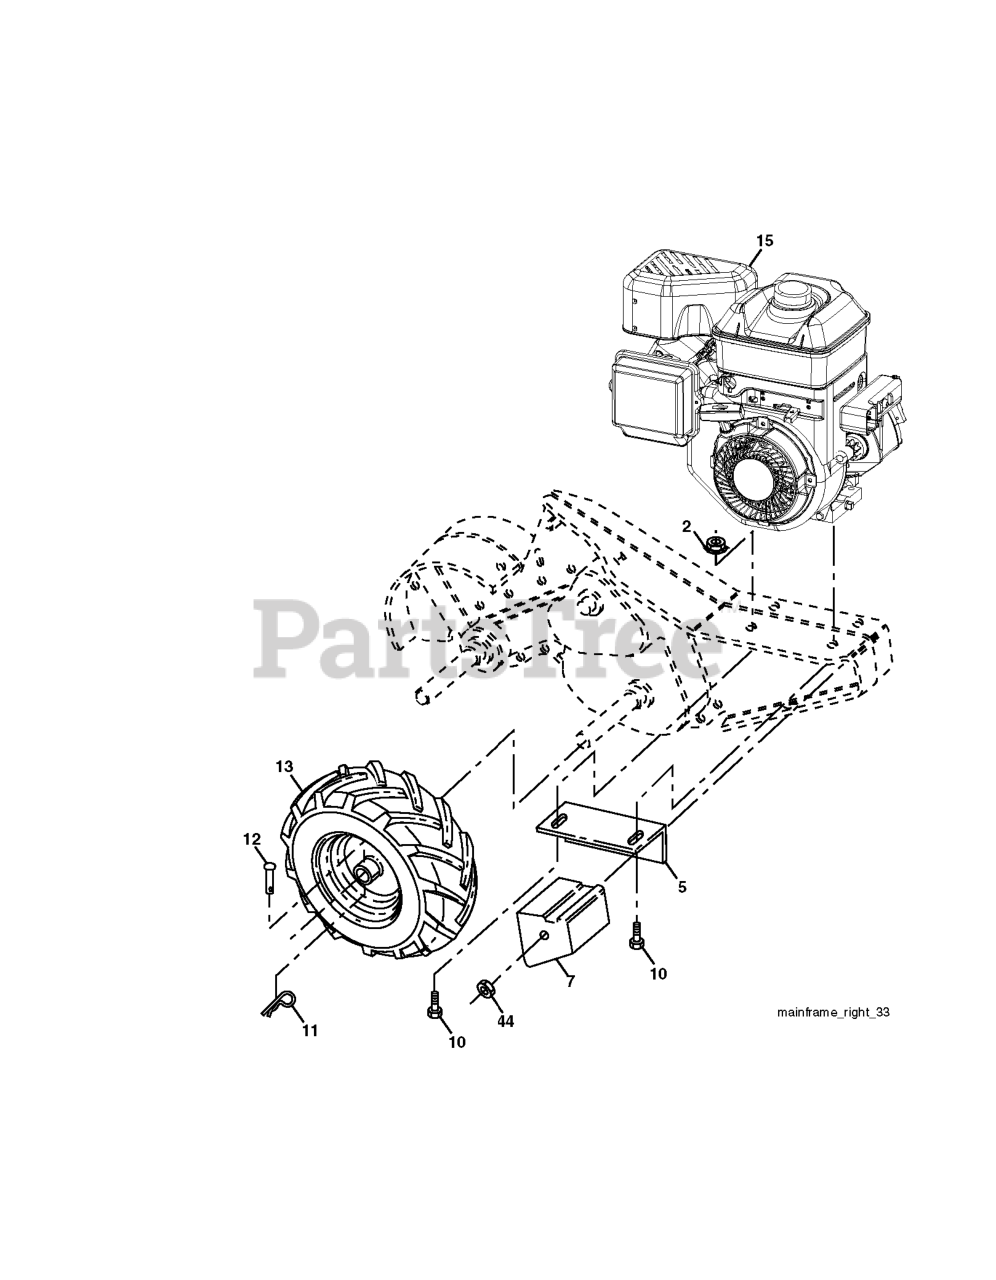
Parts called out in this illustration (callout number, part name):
2	LOCKNUT-FLANGE 5/16-18
5	DNO BRACKET RH CRT
7	COUNTERWEIGHT, RH
10	BOLT
11	RETAINER M
12	RIVET,DRILLED
13	TIRE.13X5-6.CHEVRON.TILLER
